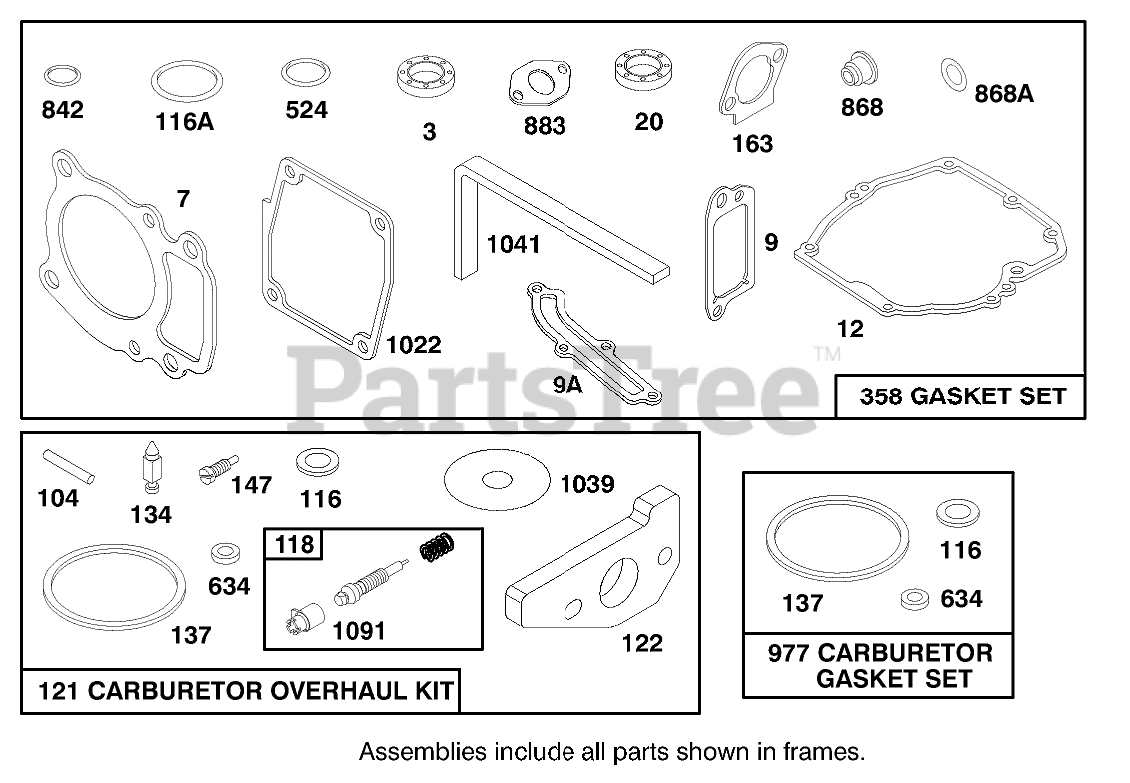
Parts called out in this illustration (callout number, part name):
3	SEAL - OIL
7	CYLINDER HEAD GASKET
9	BREATHER GASKET
9A	GASKET-BREATHER
12	ENGINE BASE GASKET
20	SEAL-OIL
104	FLOAT HINGE PIN
116	O RING SEAL
116A	O RING SEAL
118	VALVE/SPRING - NEEDLE
121	KIT-CARBURETOR OVERHAUL
122	ADAPTER ASSEMBLY
134	Valve-Inlet (Includes Seat)
137	FLOAT BOWL GASKET
147	JET - PILOT
163	AIR CLEANER GASKET
358	GASKET SET
524	O-RING
634	SEAL WASHER
842	O-RING
868	SealAssy-Valve
868A	Seal-Valve
883	EXHAUST GASKET
977	CARBURATOR GASKET SET
1022	ROCKER COVER GASKET
1039	FLOAT LIMITER
1041	SEAL - FOAM
1091	CAP - LIMITER
